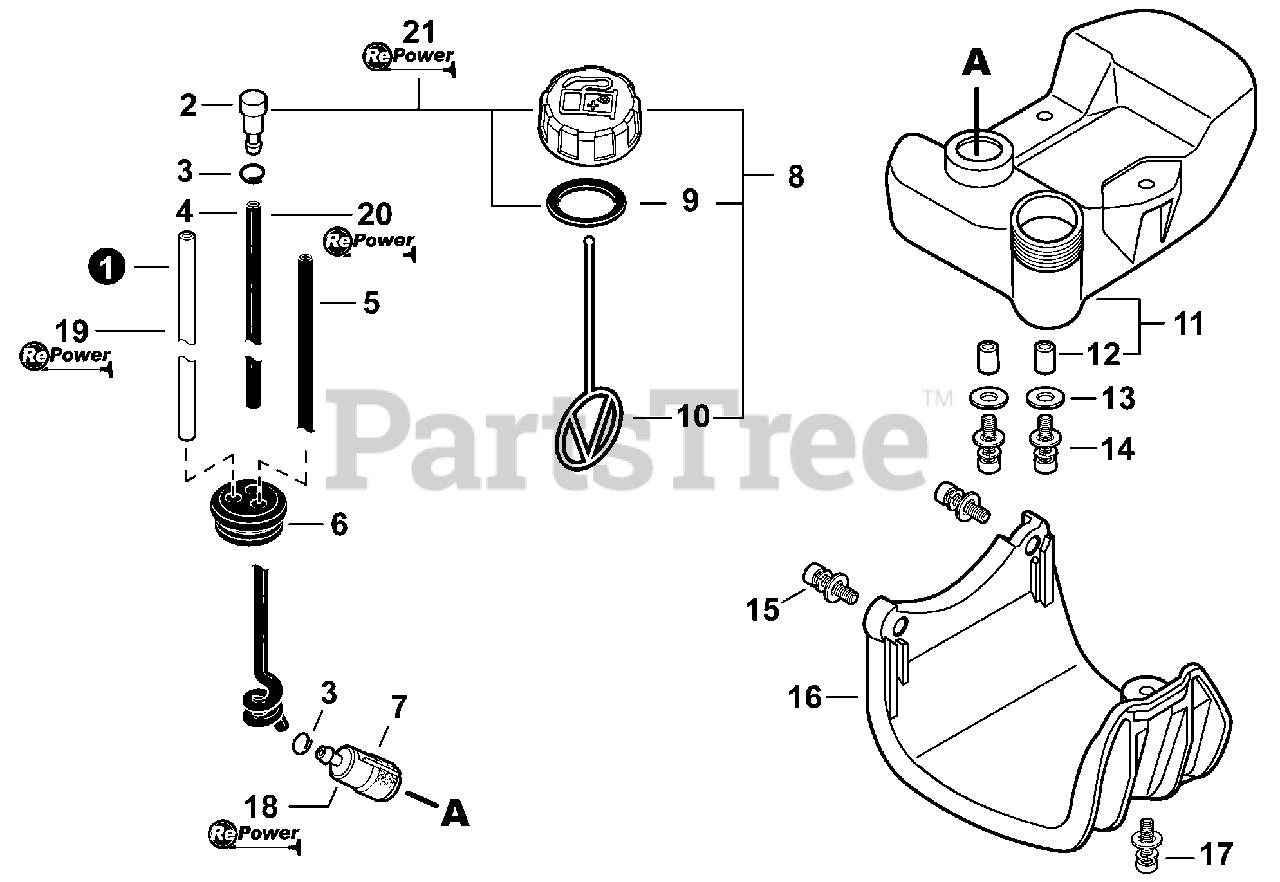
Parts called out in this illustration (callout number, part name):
1	PIPE, FUEL 3×6×80 CLEAR
2	VENT ASSY
3	CLIP 6.5 MM
4	PIPE 3×6×115 BLACK
5	PIPE, FUEL 3×6×165
6	GROMMET, FUEL
7	FILTER, FUEL
8	CAP ASSY, FUEL
9	GASKET, FUEL CAP
10	CONNECTOR, CAP L= 100 MM
11	TANK, FUEL
12	SPACER 6.2×7.8×6
13	WASHER 5.5×12×0.8
14	BOLT 5×16
15	BOLT 5×22
16	GUARD, FUEL TANK
17	SCREW 5×20
18	TUNE-UP KIT - REPOWER
19	BULK PIPE - 3×6 MM CLEAR (4 PIECES×2 M)
20	BULK PIPE - 3×6 MM BLACK (4 PIECES×2 M)
21	CAP/VENT KIT - REPOWER
